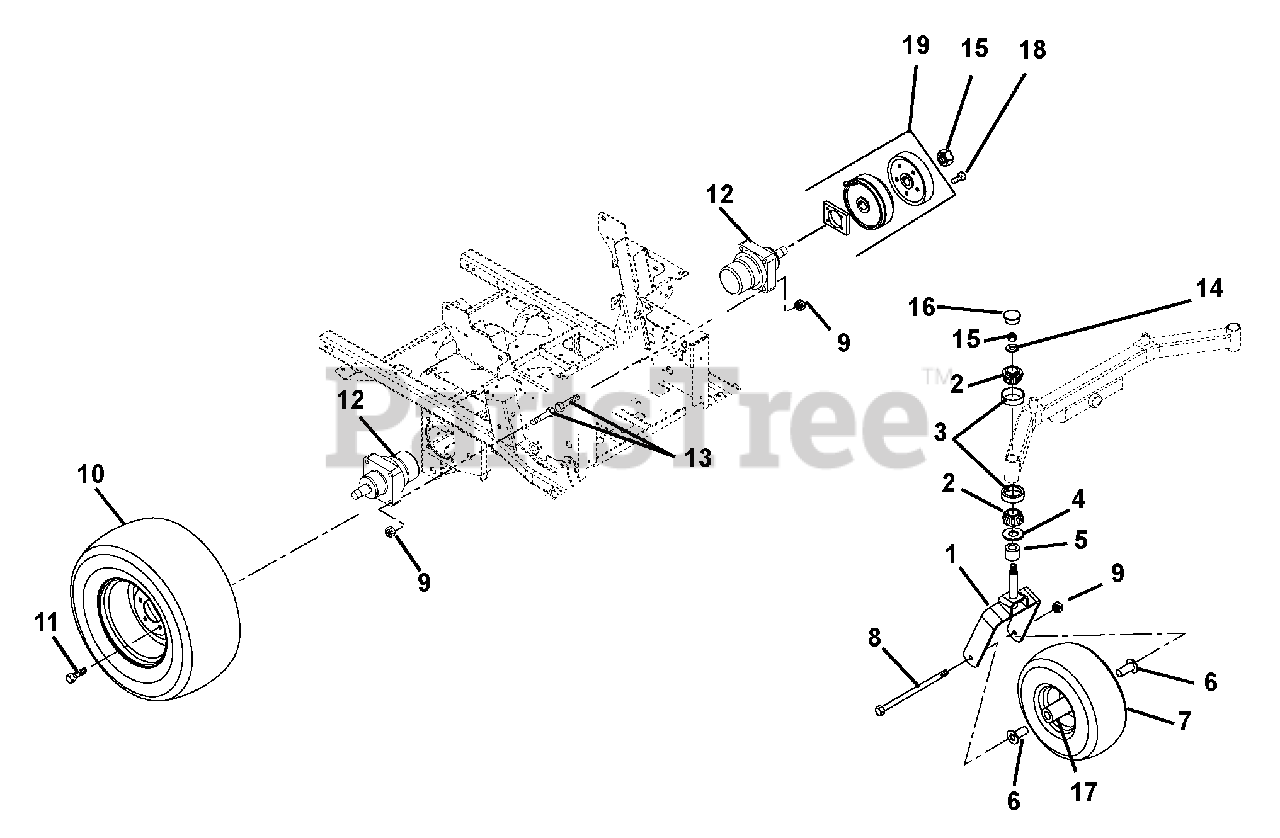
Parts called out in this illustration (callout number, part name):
1	Fork, Front
2	Bearing, Cone w/ Grease
3	Bearing, Cup 1.980 x .420
4	Bearing Seal 1.5 x 2 x .18
5	Spacer, PM, 1.03 I.D. x 1.5 O.D. x .375
6	Spacer, Wheel
7	Wheel/Tire Assembly
7	Tire, 15 x 6-6
8	Bolt, Hex .50-13 x 9.00 Grade 5
9	Nut-Locking-Top-Flange .50-13
10	Tire/Wheel Assembly 24 x 12-12
10	Tire, Turfmaster 24 x 12-12
10	Tire/Wheel Assembly 23 x 10.50-12
10	Tire/Wheel Assembly, 23 x 10.50-12
10	Tire 2 x X10.50-12 Multitrac C/S
11	Bolt, Lug .50-20 x 1.38 Grade 8, 60 Degree
12	Hydraulic Wheel Motor
13	Bolt, Wheel Motor .50-13 x 2.75
13	Bolt, Hex .50-13 x 2.75 Grade 8
14	Washer, Flat Steel, .812X1.50X.135
15	Nut, Jam Center-Lock .75-16
16	Cap, Dust
17	Bearing, 25mm I.D. x 52mm OD x 15mm
18	Bolt, Hex .31-18 x 1.5 Grade 5
19	Kit, Parking Brake Service
